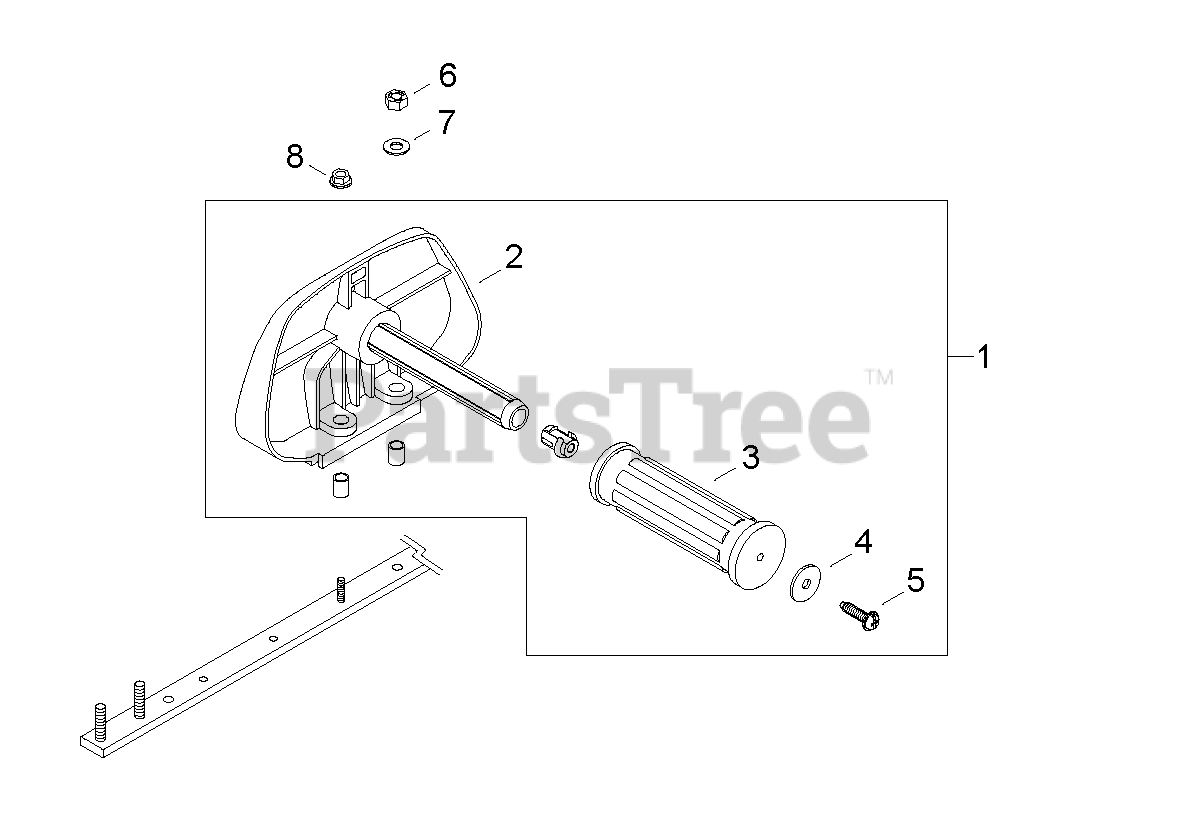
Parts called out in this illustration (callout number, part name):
1	HANDLE ASSY - FRONT
2	HANDLE - FRONT
4	WASHER - 5
5	SCREW - 5X20
6	NUT - 6
7	WASHER - 6
8	NUT - 5 -- FLANGE
